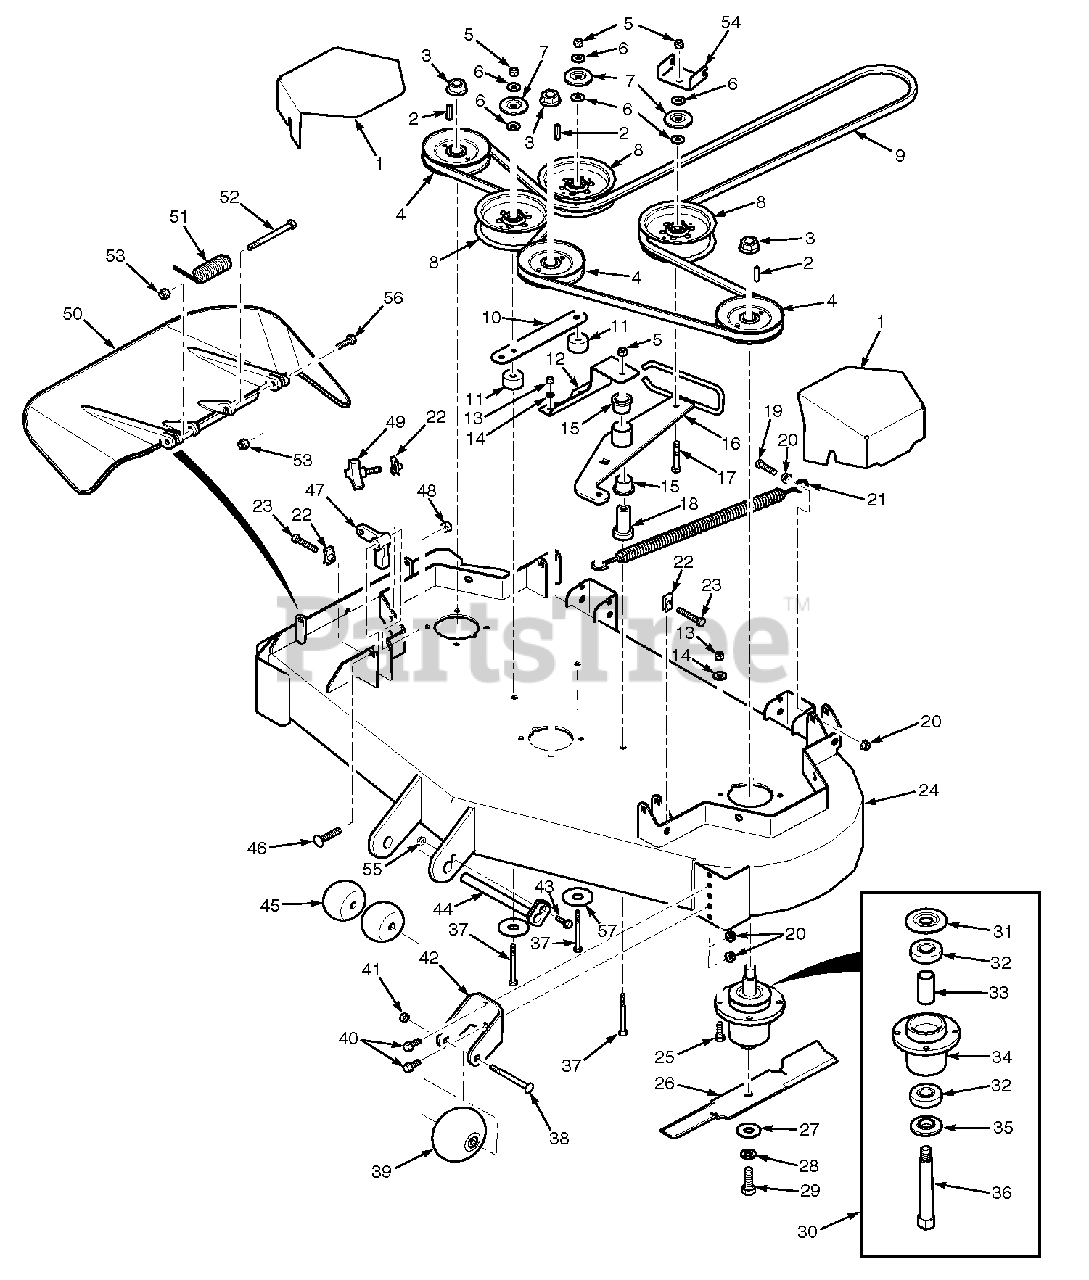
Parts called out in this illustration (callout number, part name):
1	Belt Cover
2	Key, 1/4 x 1/4 x 1-1/4"
3	Nut, 3/4-16 Spiral Lock
4	Pulley, 5.13" OD - 25mm Bore
4	Pulley, 5.73" OD - 25mm Bore
4	Pulley, 6.32" OD - 25mm Bore
5	Nut, Elastic Stop 3/8-16
6	Flatwasher, 3/8-.391 x .938 x .105
7	Dust Shield
8	Pulley, 5" Idler
9	Belt, Cutter Deck
10	Brace, Pulley
11	Spacer
12	Support, Idler Pivot
13	Nut, Elastic Stop
14	Lockwasher, 5/16 Spring
15	Bearing
16	Idler Arm
17	Bolt, Hex Head 3/8-16 x 2-1/2"
18	Pivot, Idler
19	Bolt, Hex Head 3/8-16 x 1-1/2 Gr.8
20	Nut, Serrated Flange 3/8-16
21	Spring, Idler
22	U-Nut, 3/8-16
23	Bolt, Hex Head 3/8-16 x 2" Special Lock
24	Cutter Deck w/Decals, SFZ48
24	Cutter Deck w/Decals, SFZ52
24	Cutter Deck w/Decals, SFZ61
25	Bolt, Hex Head 5/16-18 x 1-1/2"
26	Cutter Blade, 16-1/2"
26	Cutter Blade, 18"
26	Cutter Blade, 21"
27	Flatwasher, 5/8-.688 x 1.75 x .134 HD
28	Lockwasher, 1/2 Spring
29	Bolt, Hex Head 5/8-11 x 1-1/2"
30	Spindle Assembly
31	Debris Shield
32	Bearing
33	Spacer
34	Spindle Housing Assembly
35	Protector, Bearing
36	Shaft, Spindle
37	Bolt, Hex Head 3/8-16 x 3-1/2"
38	Bolt, Carriage 3/8-16 x 4"
39	Wheel, Anti-Scalp
40	Bolt, Hex Head 3/8-16 x 1" Ser. Flg.
41	Nut, Center Lock 3/8-16
42	Bracket, Anti-Scalp
43	Bolt, Hex Head 5/16-18 x 1"
44	Shaft Weldment
45	Wheel, Anti-Scalp
46	Bolt, Carriage 7/16-14 x 2-1/4"
47	Lever, Deck Level
48	Nut, Elastic Stop 7/16-14
49	Knob w/Stud
50	Discharge Chute Assembly
51	Spring, Discharge Chute
52	Bolt, Hex Head 5/16-18 x 4-3/4"
53	Nut, Elastic Stop 5/16-18
54	Bracket, Belt Guide
55	Nut, Serrated Flange 5/16-18
56	Bolt, Hex Head 5/16-18 x 1-3/4"
57	Flatwasher, 3/8-.406 x 2.25 x .1875
